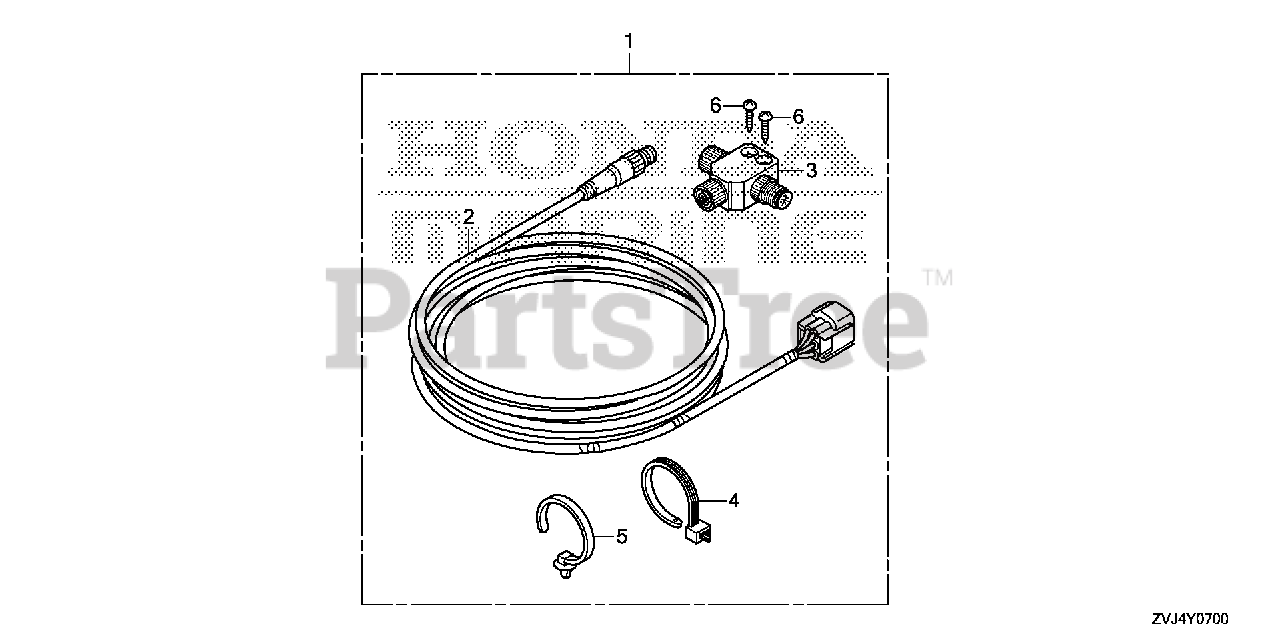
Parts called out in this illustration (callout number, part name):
1	CABLE KIT, INTERFACE (10FT)
1	CABLE KIT, INTERFACE (16FT)
1	KIT, CABLE (6FT) (NMEA)
2	CABLE ASSY., INTERFACE (10FT)
2	CABLE ASSY., INTERFACE (16FT)
2	CABLE ASSY., INTERFACE (6FT)
3	CONNECTOR (T)
4	TIE, CABLE
5	CLIP, HARNESS BAND (155.3MM) (BLACK)
6	SCREW, TAPPING (4X25)
